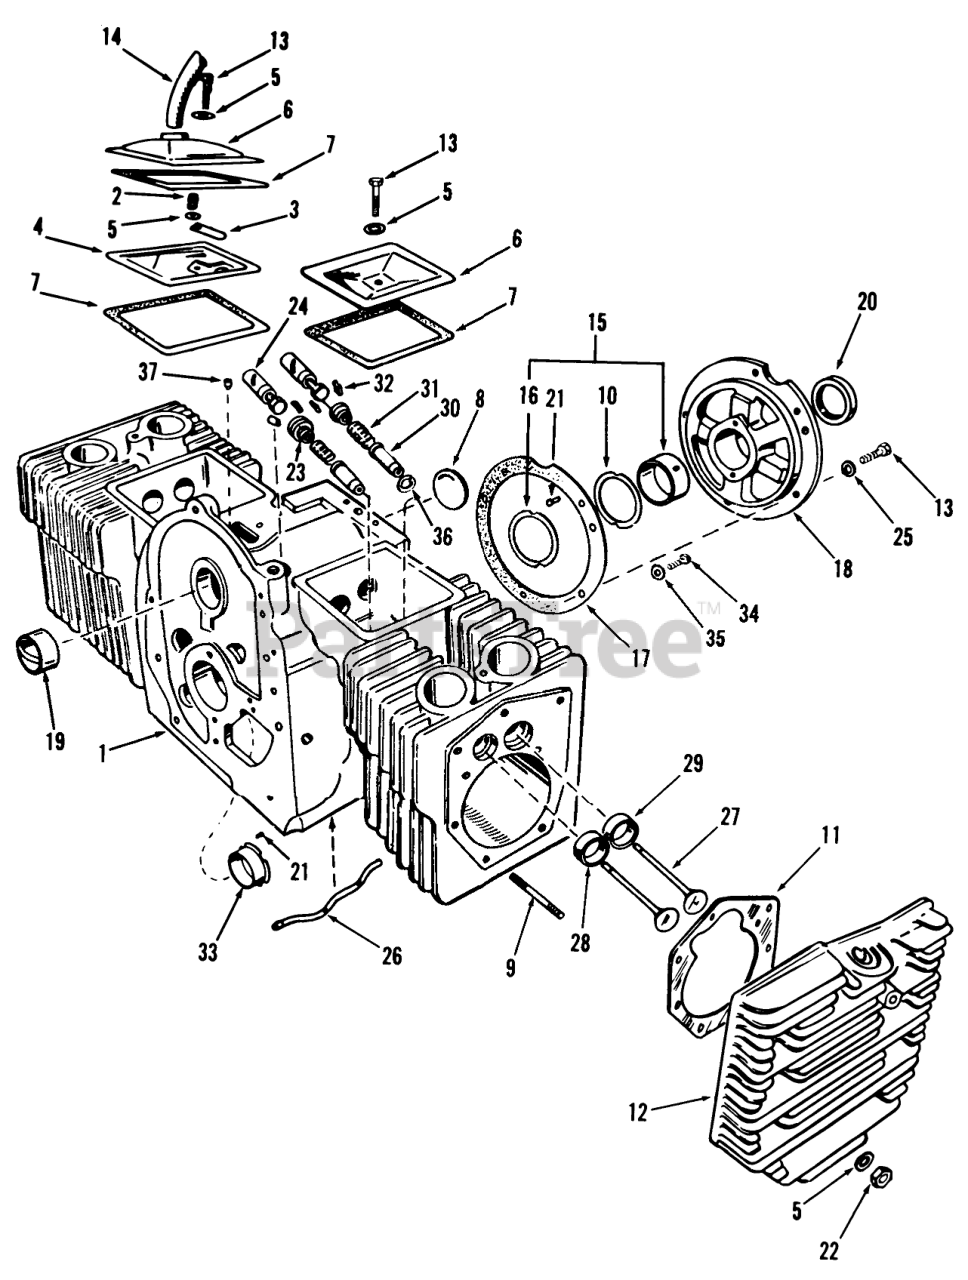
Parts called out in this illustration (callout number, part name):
1	Short Block
1	Block Assy
2	Spring, Breather Valve
3	Breather Valve
4	Breather Baffle
5	Washer, Cyl Head Screws 5/16 in
5	Washer, Valve Compartment 1/4 in.
5	Breather Valve (1/4"-Steel)
6	Cover With Tube Opening LH
6	Cover W/O Tube Opening RH
7	Valve Cover Gasket
8	PlugCamshaft Expansion
9	Cylinder Head (5/16 x 2 5/16")
9	STUD-CYL HEAD
10	Rear Bearing Shim
11	Gasket-Cylinder Head
12	Cylinder Head RH
12	Cylinder Head LH
13	Cap Screw-Valve Cover
13	Cap Screw-Bearing Plate
14	TUBE-BREATHER
15	.020" Undersize
15	.010" Undersize
15	.002" Undersize
15	Standard
15	.030" Undersize
16	Cranksft Bearing Thrust Washer
17	Gasket, Bearing Plate
18	Bearing Plate
19	Camshaft Bearing (Precision)
20	Bearing Plate Seal
21	Pin-Main Bearing Stop
22	Cylinder Head-Hex (5/16-24)
23	Valve Spring Retainer
24	.002" Oversize
24	.001" Oversize
24	Standard
24	.005" Oversize
25	Lockwasher-Rear Bearing Plate
26	Crankcase Oil Tube
27	Intake
27	VALVE-EXHAUST
28	.005" Oversize
28	.002" Oversize
28	Standard
28	.025" Oversize
28	55095 ADD.REPLAC.PA
29	.002" Oversize
29	Standard
29	.025" Oversize
29	.010" Oversize
29	.005" Oversize
30	Valve Guide
31	Valve Spring
32	Lock-Valve and Spring Retainer
33	.002" Undersize
33	Standard
33	.030" Undersize
33	.020" Undersize
33	.010" Undersize
34	Cap Screw-Cylinder Block
35	Copper Washer 3/8-Oil Pressure
36	Gasket-Intake Valve Guide
37	Breather Hole Plug
